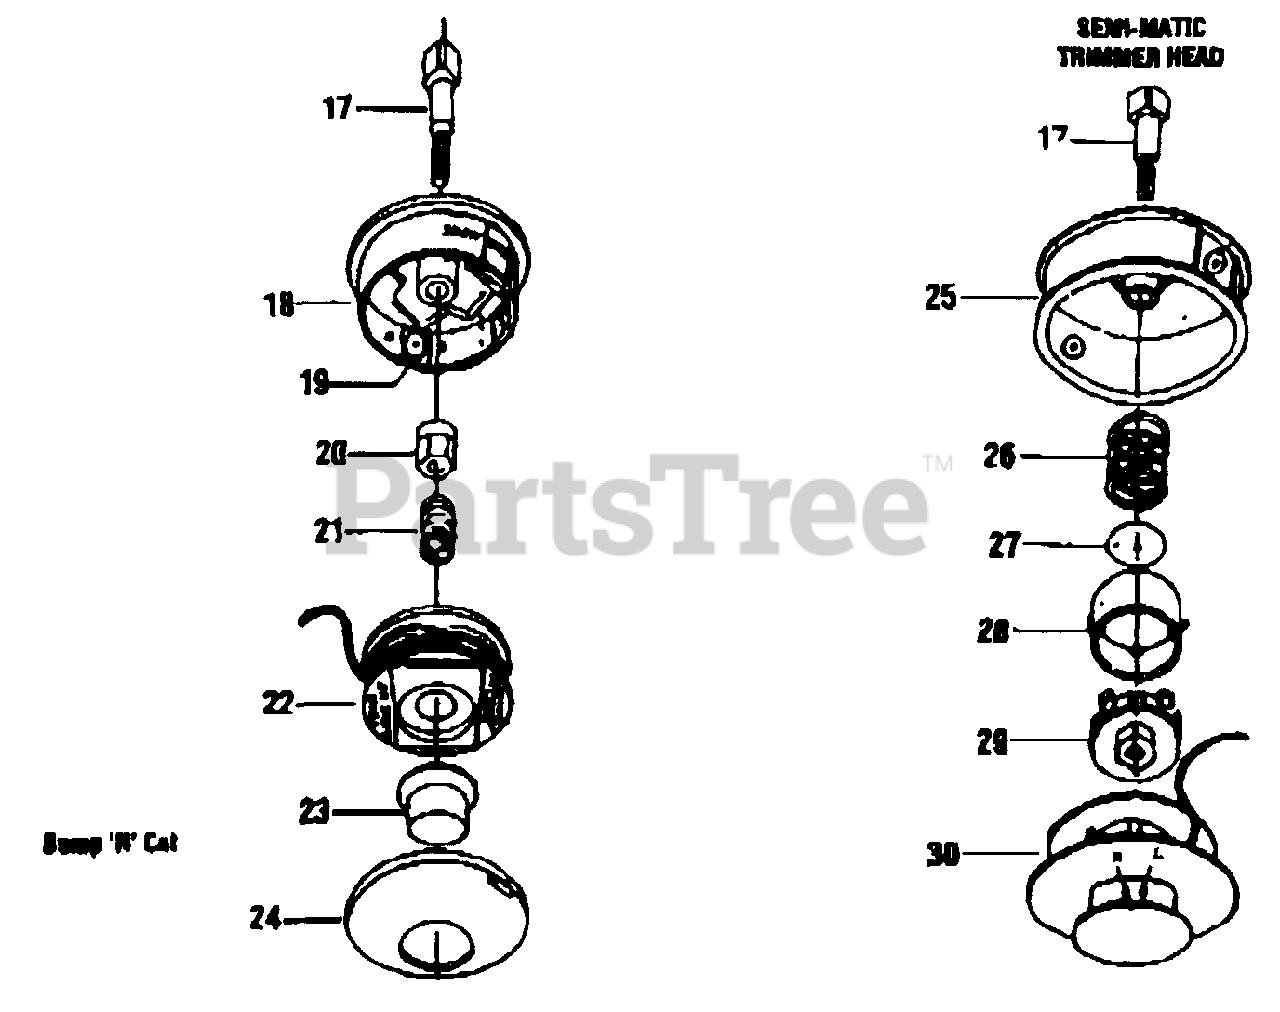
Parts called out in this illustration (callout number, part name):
17	BOLT, SHAFT - 8 -- LEFT HAND
22	SPOOL - LEFT
23	BUTTON
24	COVER
28	DRIVE - OUTER
29	CAM, INNER - LEFT
